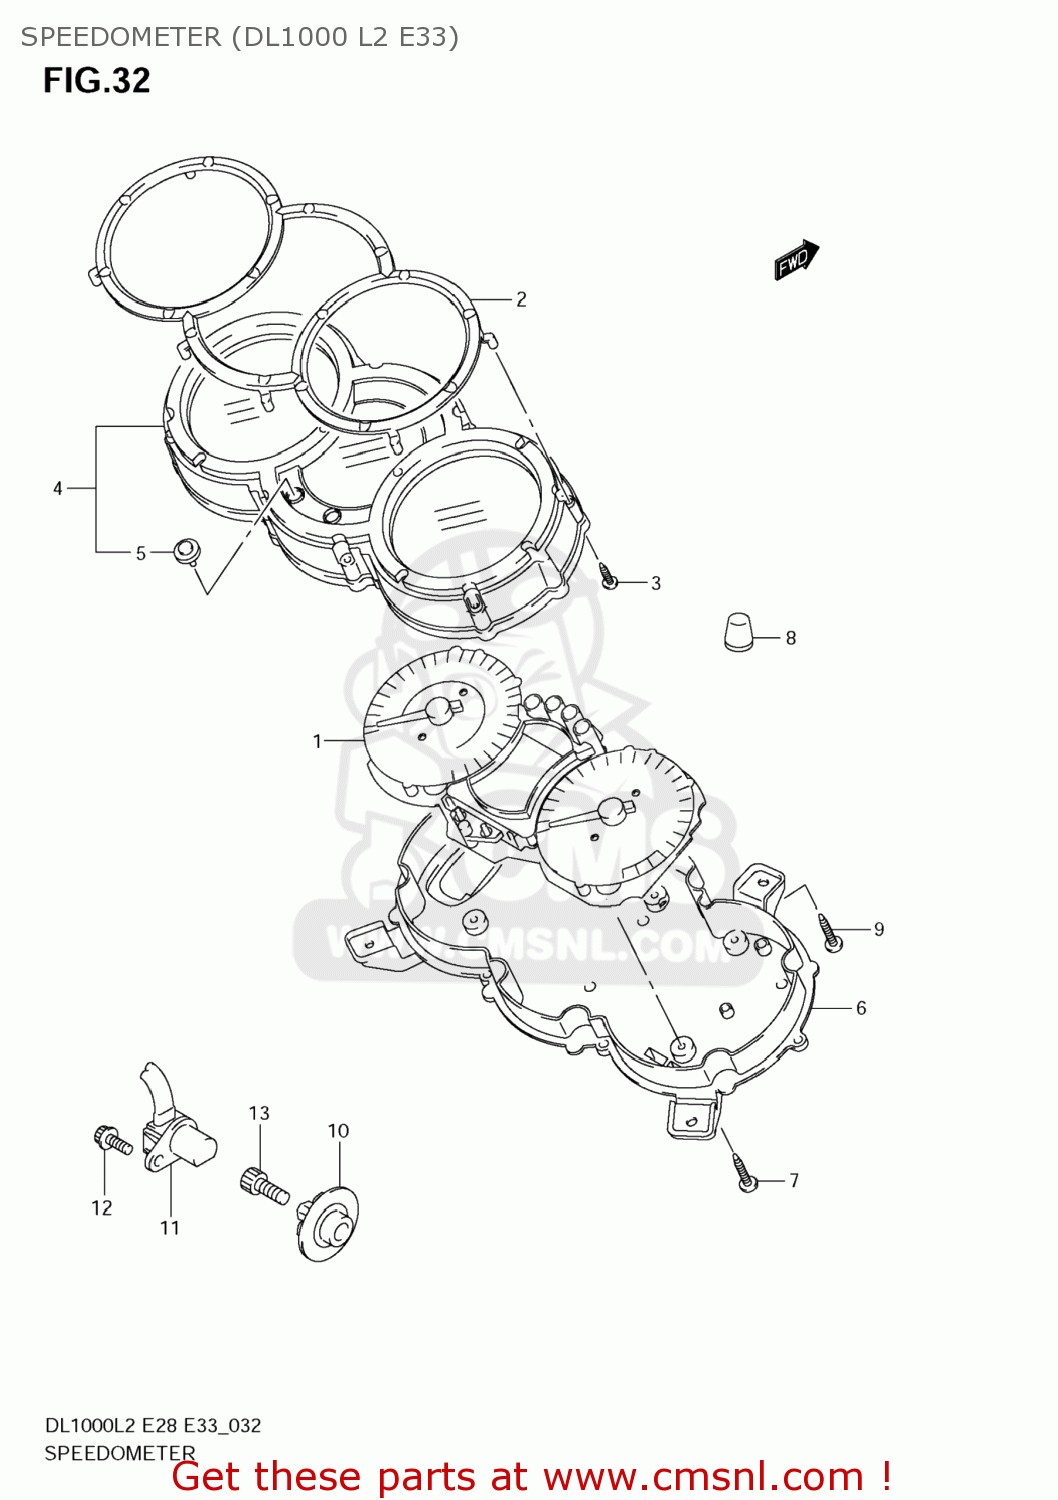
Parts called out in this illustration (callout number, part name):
1	SPEEDOMETER
2	RING
3	SCREW(2.3X8)
4	CASE,UPR
5	SWITCH,LEVER
6	CASE,LWR
7	SCREW(3X16)
8	CUSHION,SPEEDOMETER
9	SCREW
10	ROTOR,SPEED
11	SENSOR,SPEED
12	BOLT
13	BOLT
